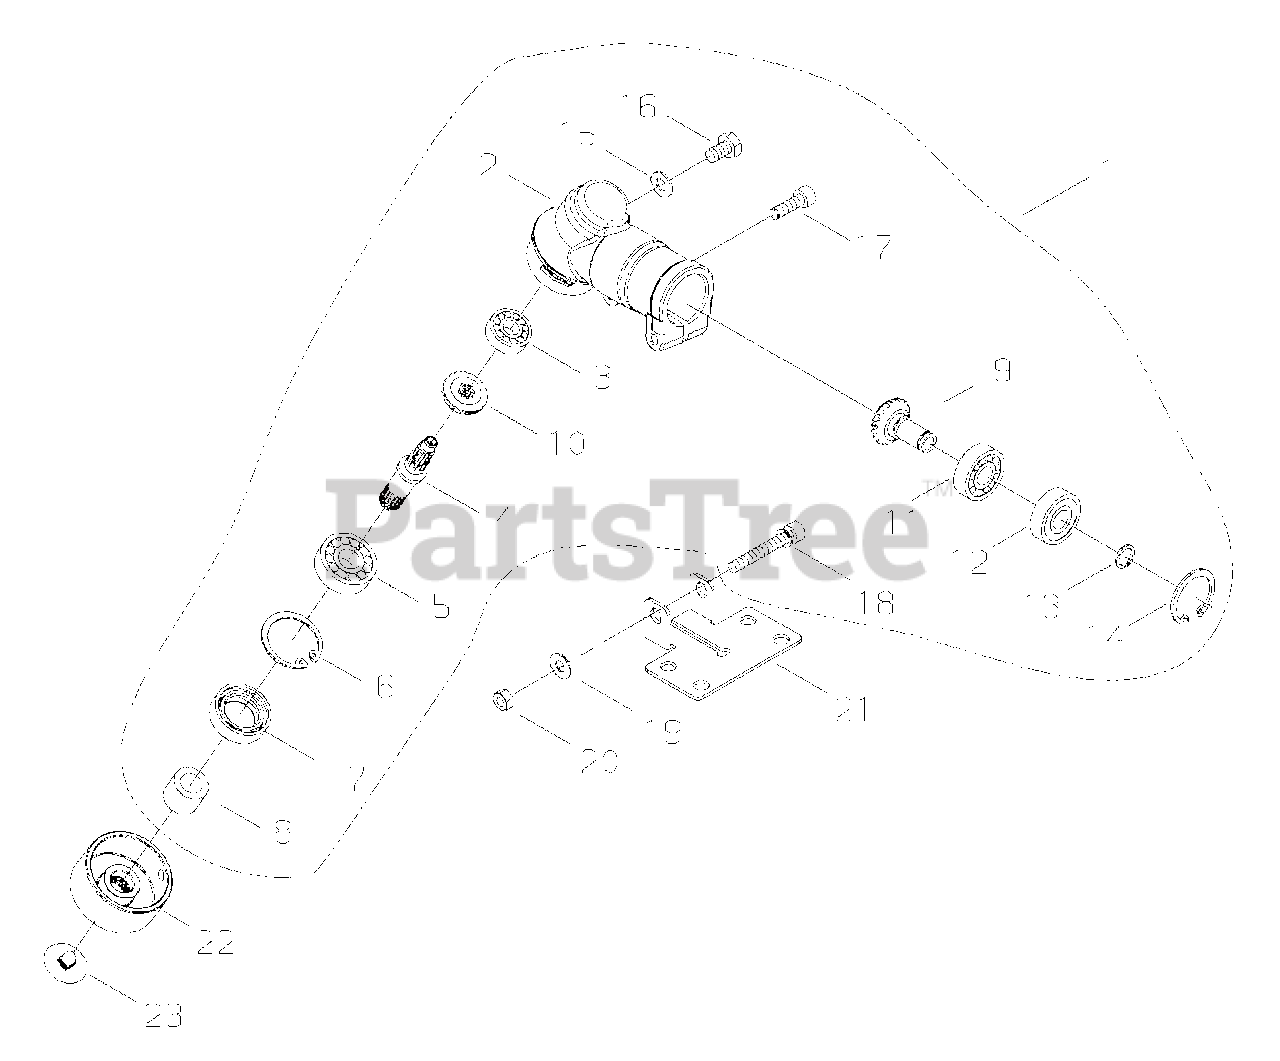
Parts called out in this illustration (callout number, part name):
1	GEAR CASE ASSY
2	CASE, GEAR
3	BEARING, BALL - 626MOS
4	GEAR - SHAFT
5	BEARING, BALL - 6000MOS
6	RING, RETAINING - 26
7	SEAL, OIL
8	COLLAR
9	GEAR - SHAFT
10	GEAR - BEVEL
11	BEARING, BALL - 609 MOS
12	BEARING, BALL - 609Z MOS
13	RING, RETAINING - 9
14	RING, RETAINING - 24
15	WASHER - 6
16	BOLT - 6X10
17	SCREW - 5X10
18	SCREW - 5X40
19	WASHER - 5
21	MOUNTING PLATE, SHIELD
22	HOLDER
